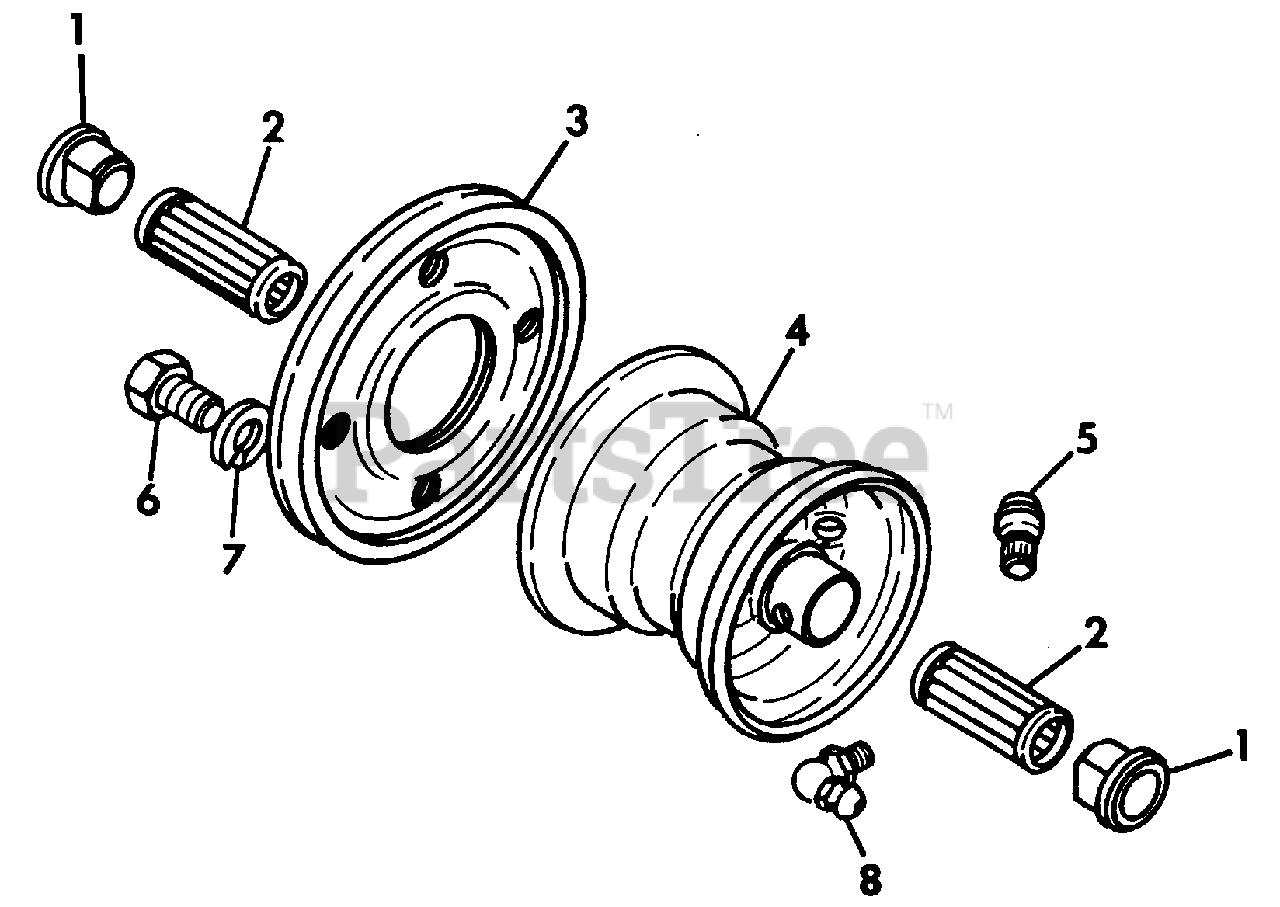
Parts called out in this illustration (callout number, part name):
1	BEARING, FLANGE
2	BEARING, 7/8X2.50
3	ASSEMBLY, PULLEY AND BRAKE DRUM
4	ASSEMBLY, WHEEL
5	ASSEMBLY, VALVE STEM
6	BOLT, HEX 5/16-18X.75
7	WASHER, LOCK 5/16 REG.
8	FITTING, LUBE 90 DEG.
